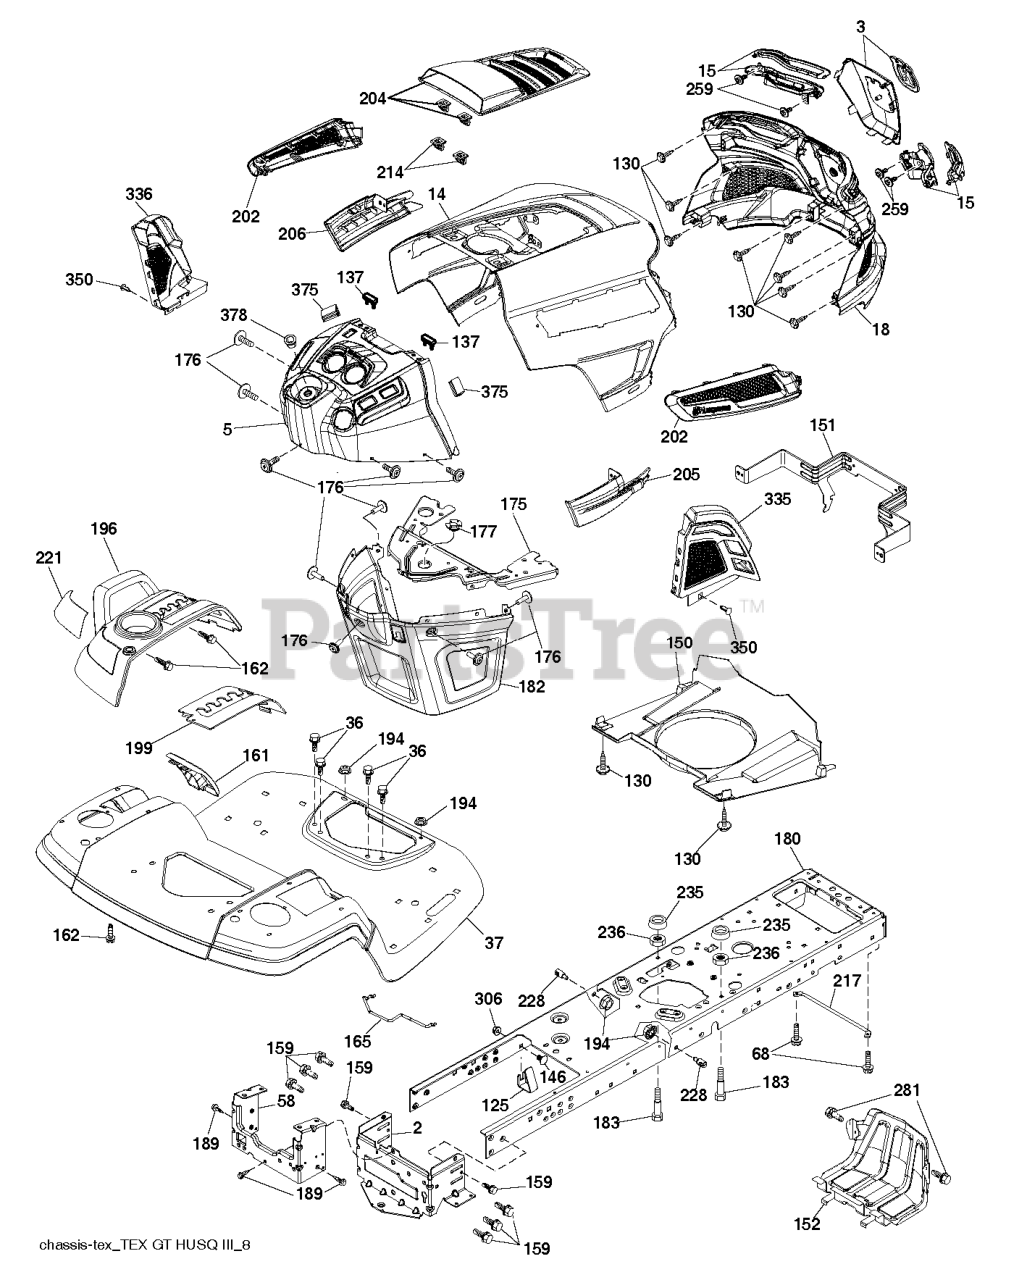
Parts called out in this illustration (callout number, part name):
2	DRAWBAR.LOWER.2PC.18/22
3	Covers
5	DASH.UPR.GT2.DUAL.RD.PT
14	HOOD.ASM.HUSQVARNA.GT.TEX.ORAN
15	Service Kit
36	SCREW 5/16"
37	FENDER.PNT.TX.GT.CH/FW/DL.HUSQ
58	DRAWBAR.UPPER.2PC,LRG.FENDER
125	CLIP.FUEL.LINE
137	BUMPER DASH
146	BOLT.RDHD.SHT.SQNK.3/8-16X5/8
150	AIR.DUCT.GTV.BLACK
151	BRACKET.PIVOT.HOOD.GT.HUSQ.II
152	SHIELD.BROWNING.PNT.GT.V2
159	SCREW, 3/8-16X3/4
161	CONSOLE.WINDOW.FUEL.HUSQ.GT
162	SCREW.HI-LO.CONSOLE
165	SUPPORT.TANK.REAR.B/TE
175	PLATE.PNT.CROSSMEMBER.HUSQ/PRE
176	SCREW.#10-24X5/8.RN.QU
177	BUSHING STEERING
180	CHASSIS.LT/GT.BOLTED
182	DASH.LOWER.COMMON.12V.ADAPTOR
189	SCREW
196	SUBASM.CONSOLE.HUSQ.GT.DECKLFT
199	PLATE.DECK.LIFT.HUSQVARNA.GT
202	Vents
205	SIDE.TRIM.RH.GT.HUSQ.II
206	SIDE.TRIM.LH.GT.HUSQ.II.GRAY
214	CLIP.RETAINER.TINNER.
217	ROD.PIVOT.HOOD
221	REFLECTOR.LH.TEX GT HU
228	STUD.FASTNER.W/ANTI-ROTATE
236	NUT.CENTERLOCK.5/16-
281	SCREW 3/8-16X1
306	NUT LOCK FLG 3/8-16 UNC
335	COVER.LOWER.DASH.RH.BLACK
336	COVER-LH.LOWER.DASH.GT2.BLACK
350	CLIP.X-MAS.TREE
375	BUMPER CLIP-ON. DASH 1"
378	BUSHING FLANGE; PLASTIC
